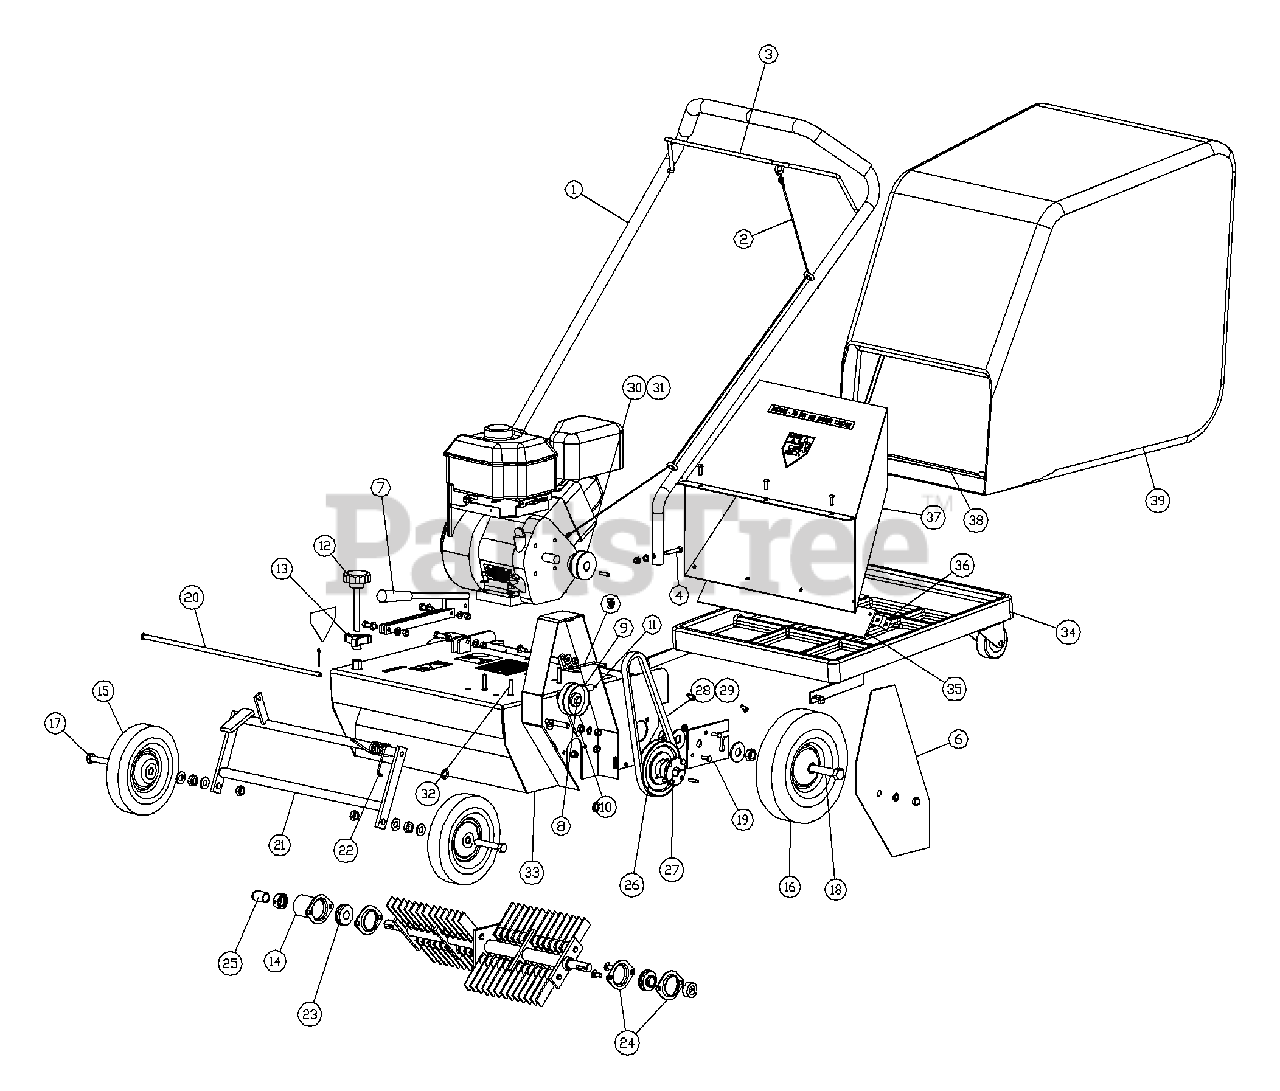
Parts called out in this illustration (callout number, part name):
1	Handle Assembly.
2	Clutch Cable Assembly.
4	Bolt kit, handle
5	Belt keeper kit
6	Belt Guard Kit
7	Depth Lever Assembly.
8	Idler Assembly Kit
9	Pulley, idler 2 3/4 OD
10	Mounting Arm, idler pulley
11	Spring, ider return
12	Depth Adjustment Knob
13	3 - pronged lock depth knob
14	Rotor guard
15	Front Wheel, 8 x 1 3/4, ball bearing
16	Rear Wheel, 10 x 2 3/4, ball bearing
17	Bolt kit for front wheel
18	Bolt kit for rear wheel
19	Wheel plate kit
20	Lift Arm Rod Kit
21	Lift Arm Assembly Kit
22	Torsion spring
23	Bearing, 3/4 with locking collar
24	Stamping Kit
25	Rotor cap, 3/4 ID
26	V - Pulley, B-5.0 OD, tapered bore
27	Bushing kit
28	V - Belt, B-34, special
29	V-Belt, B36, special
30	V - Pulley engine kit for 3/4 bore
31	V - Pulley engine kit for 1" bore
32	Engine Bolt Kit
33	Deck, DT18
34	Bagger platform kit
35	Neoprene chute 3/16 x 20.5
36	Chute kit
37	Chute weldment kit
38	Bagger frame
39	Catcher bag
